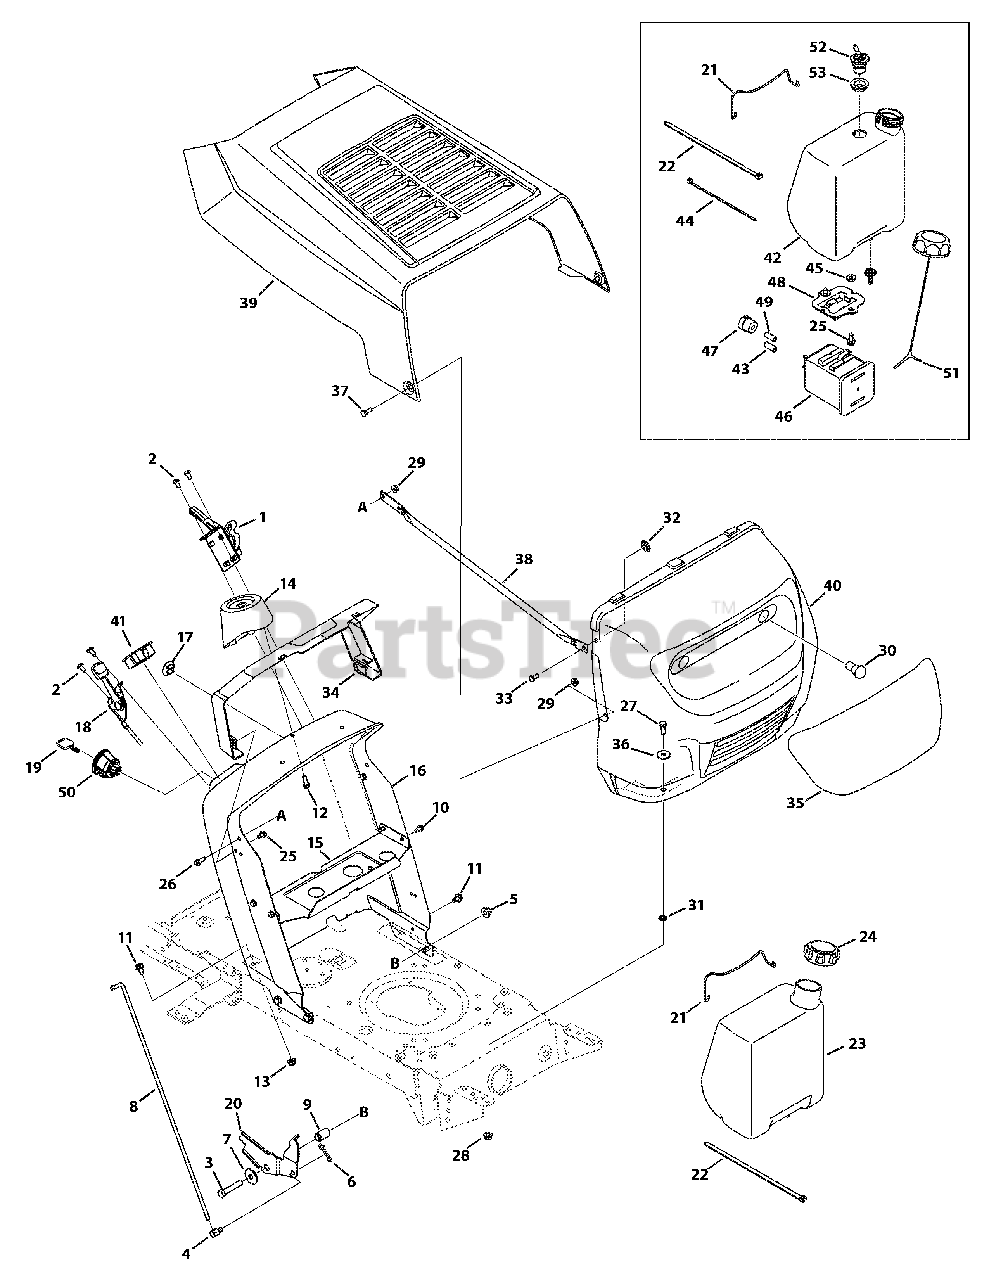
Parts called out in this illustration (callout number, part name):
1	7-Speed Control Assembly
1	6-Speed Control Assembly
2	Screw, 1/4-20 x .500
3	Hex Screw, 3/8-16 x 2.0
4	Ferrule, 1/4-20 x 1.00
5	Flangelock Nut, 3/8-16
6	Bow Tie Cotter Pin, 72
7	Flat Washer, .411 x 1.25 x .100
8	Speed Selector
9	Flange Spacer, .390 x .671 x 1.095
10	Hex Washer Screw, 1/4-20 x .500
11	Screw, 5/16-18 x .625
12	Screw, 1/4-15 x .750
13	Flangelock Nut, 5/16-18
14	Steering Support
15	Gas Tank Support Bracket
16	Dash, RMC
17	Choke Plug
18	Throttle/Choke Cable
20	Speed Latch. RMC
21	Battery Assembly Rod
22	Cable Tie
23	1.5 Gallon Fuel Tank
24	Fuel Cap
25	Screw, 5/16-18 x .750
26	Screw, 1/4-20 x .750
27	Hex Screw, 5/16-18 x .75
28	Flangelock Nut, 5/16-18
29	Flangelock Nut, 1/4-20
30	Miniature Lamp 12V Socket
31	Speed Nut, .3125
32	Push-On Nut, .25
33	Flat Head Rivet, 1/4"
36	Flat Washer, .344 x 1.0 x .063
37	Shoulder Bolt, 1/4-20 x .375 x .125
41	Ammeter
42	Fuel Tank, 1.36 Gallons
43	Fuel Hose, Yellow
44	Cable Tie
45	Flat Washer, .344 x .750 x .120
46	5 Gallon Carbon Canister
47	Vent Filter Canister
48	Canister Adaptor Bracket
49	Fuel Hose, White
50	Key Switch
51	Fuel Cap, 2.25"
52	Rollover Valve
53	Rubber Grommet, 23 x 3.55
